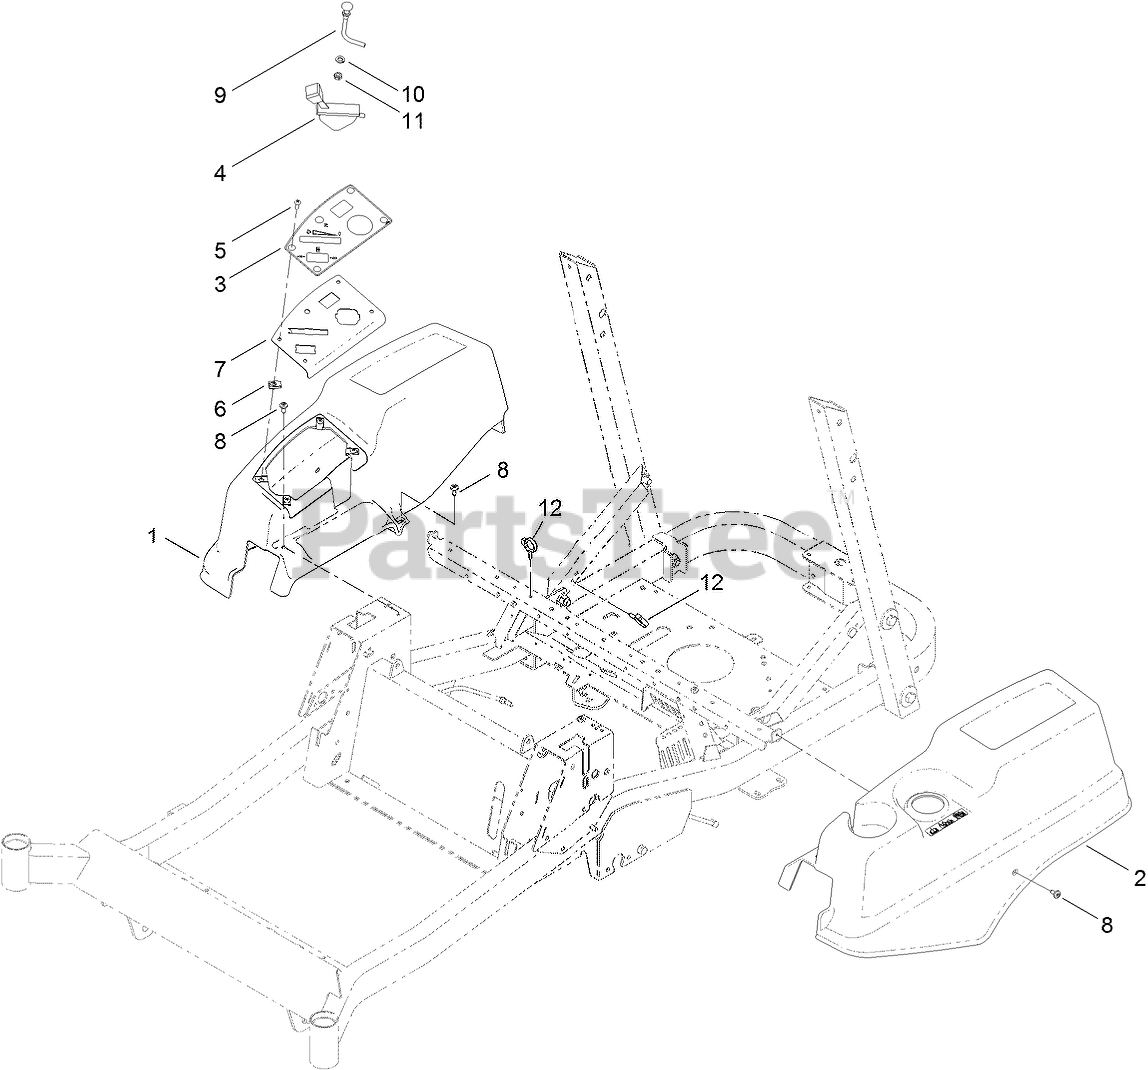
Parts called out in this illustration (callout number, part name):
1	POD-RH
2	POD-LH
3	DECAL-PANEL, CONTROL
4	CABLE-THROTTLE
5	SCREW-PRH
7	PANEL-CONTROL
8	SCREW-SHOULDER
9	CABLE-CHOKE
10	WASHER-LOCK
11	NUT-HJ
12	CLAMP-HOSE
